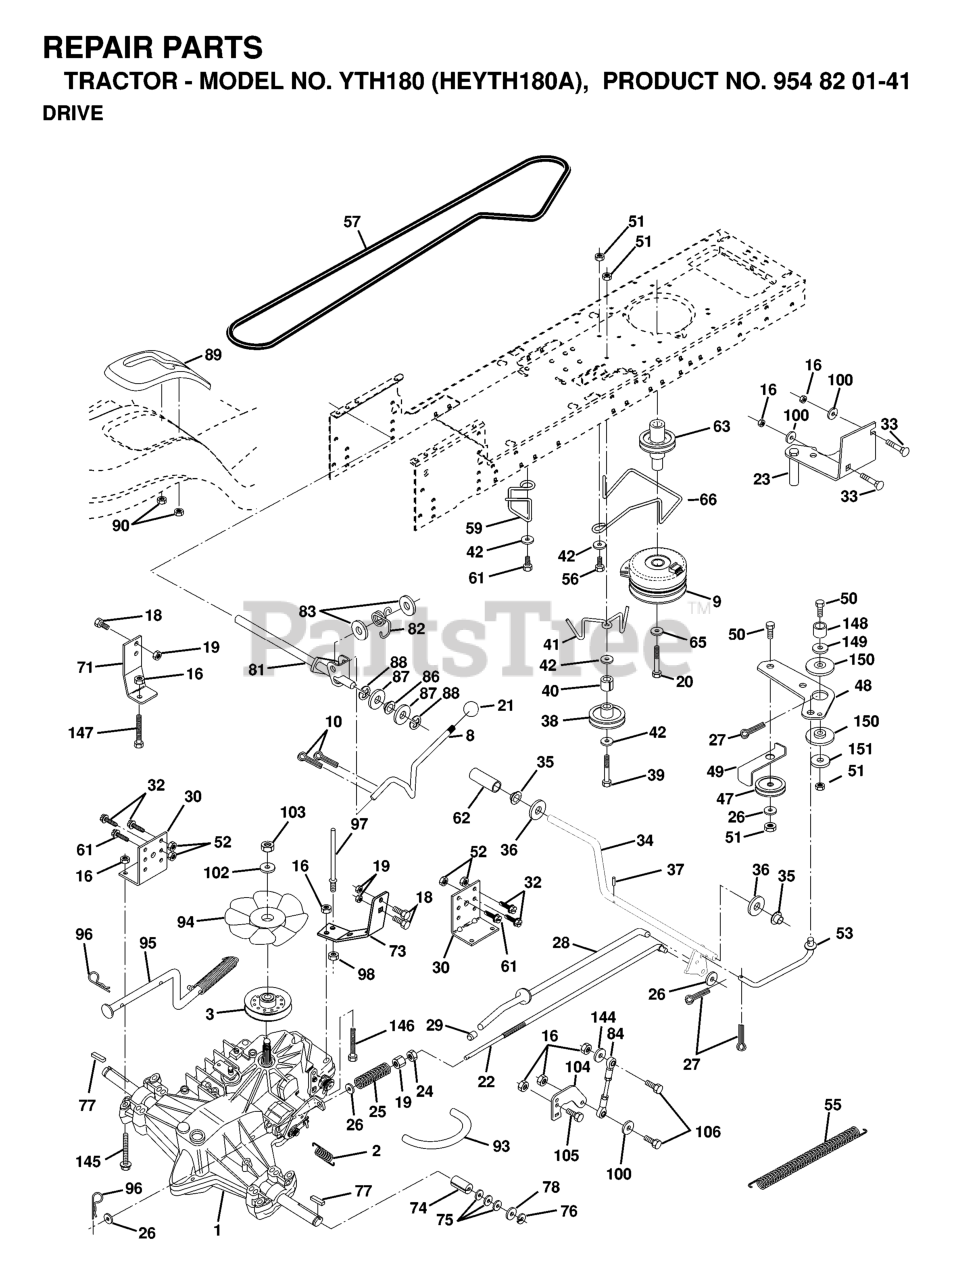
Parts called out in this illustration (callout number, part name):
2	SPRING BRAKE
3	PULLEY, TRANSAXLE
8	ROD SHIFT FENDER
9	ELECTRIC CLUTCH
10	PIN COTTER
16	NUT.71038.31-18.HEX.NYLOCK
19	NUT
20	BOLT HEX
21	KNOB.DUCKHEAD.1/2
22	ROD BRAKE HYDRO
23	BRACKET, ASM CLUTCH MTG
24	NUT
25	SPRING ROD LT
26	WASHER
27	COTTER PIN
28	ROD BRAKE PARK LT
29	PLUNGER CAP
30	BRACKET TRANSAXLE
32	BOLT
33	RP BOLT 5/16-18 X3/4 ZN/YEL GR
34	SHAFT, FOOT PEDAL
35	BEARING.NYLON
37	DRIVE PIN
38	FLAT IDLER PULLEY
41	KEEPER.BELT.IDLER.FLAT
42	WASHER
47	IDLER PULLEY
48	BELLCRANK, CLUTCH
49	RETAIN BELT
50	BOLT
52	LOCKNUT
53	LINK, CLUTCH LT
55	SPRING, RETURN LT
57	BELT
59	KEEPER CENTER SPAN
61	SCREW
62	COVER, PEDAL (1 2)
63	PULLEY, CLUTCH ELECT EVX
65	LOCKWASHER
66	KEEPER BELT ENGINE
71	STRAP LH TORQUE
73	STRAP TORQUE RH HYDRO
74	SPACER SPLIT
77	SQUARE KEY
81	SHAFT ASSY
82	SPRING,TORSION
83	WASHER
89	SHIFT CONSOLE
90	NUT.PUSH.3/16
93	LINE FUEL HYD 4"
94	FAN 7" HYDRO
95	CONTROL ARM, BYPASS HYDRO
96	RETAINER M
97	KEEPER BELT RH
100	WASHER M
103	NUT.HEX.1/2-20
104	CONTROL ARM
106	BOLT.5/16-18X1-1/4 FULL.THREAD
144	Washer 11/32 x 5/8 x 16 Ga SD
146	Bolt Hex Flanged 5/16-18 Unc x 2
147	Bolt Hex Flanged 5/16-18 Unc x 2
149	SPACER RETAINER
150	BUSHING NYLON COLLERED
151	WASHER 12/32X2X10GA
